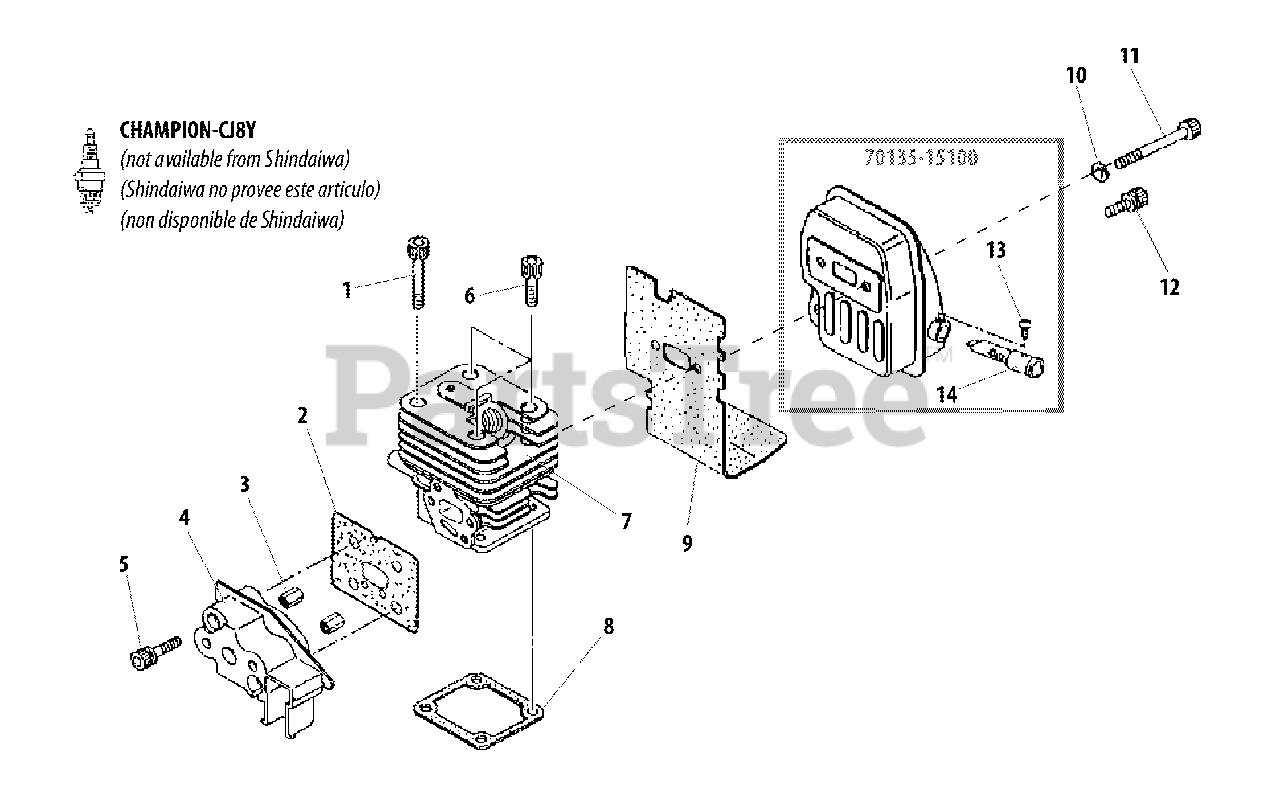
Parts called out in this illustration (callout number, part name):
1	BOLT M5×35
2	GASKET
3	NUT
4	INSULATOR
5	BOLT SS M5×30
6	BOLT M5×16
7	CYLINDER
8	GASKET, CYLINDER
9	GASKET, EXHAUST
10	WASHER, FLAT 5.5×10×0.8
11	BOLT M5×50
12	BOLT 5×12
13	SCREW, TAPPING 3×6
14	SCREEN, SPARK ARRESTER
A	MUFFLER ASSY
